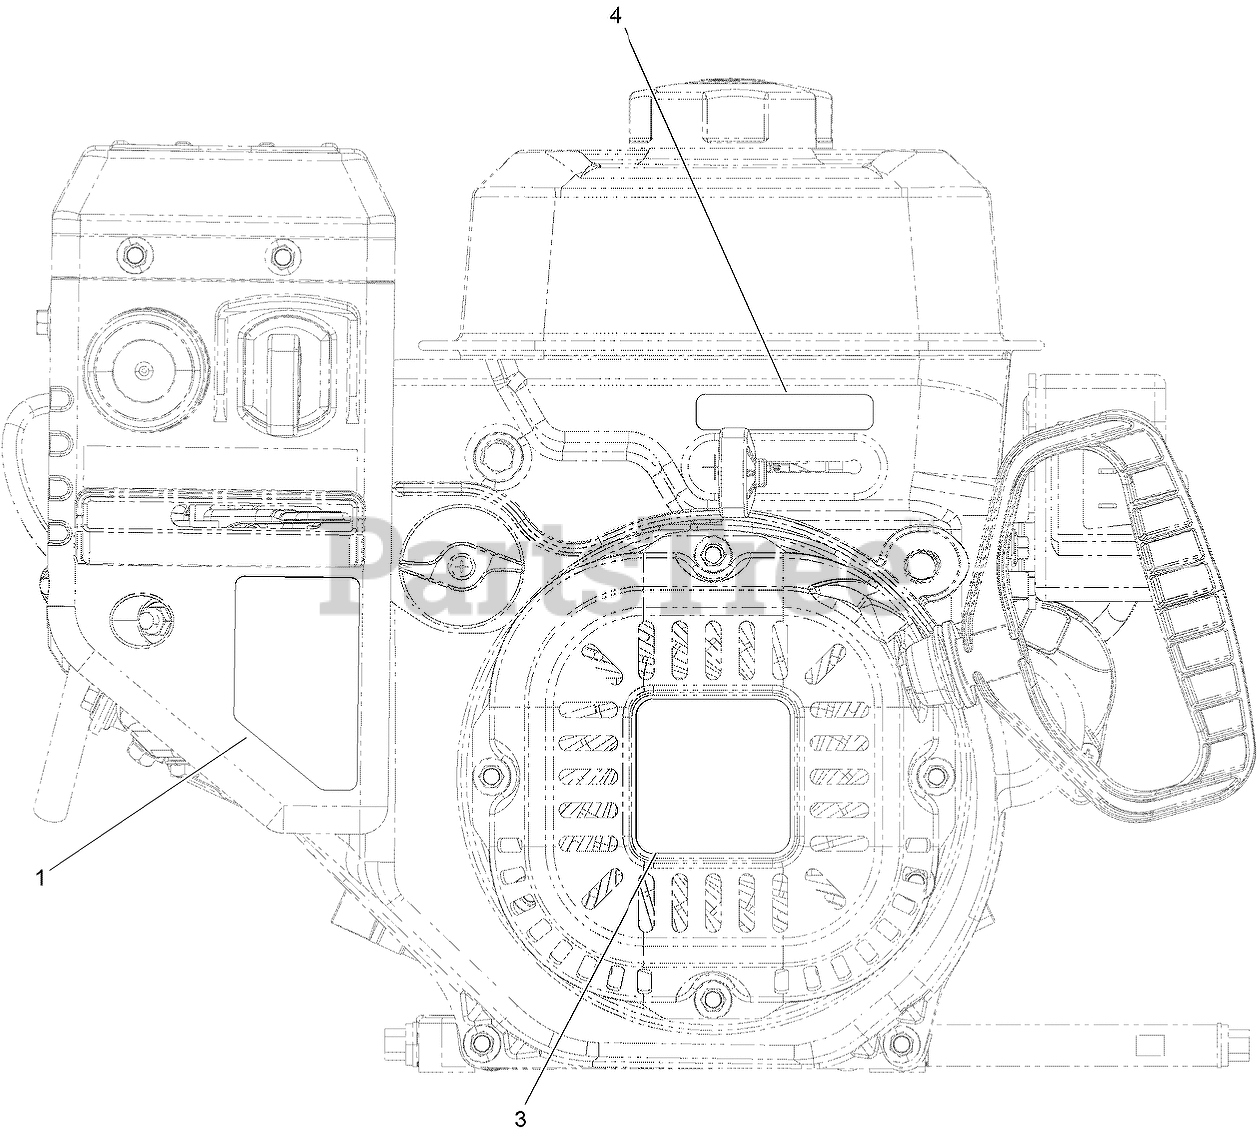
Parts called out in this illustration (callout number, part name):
1	DECAL-CONTROL, ENGINE
3	DECAL-RECOIL, G250
4	DECAL-THROTTLE
